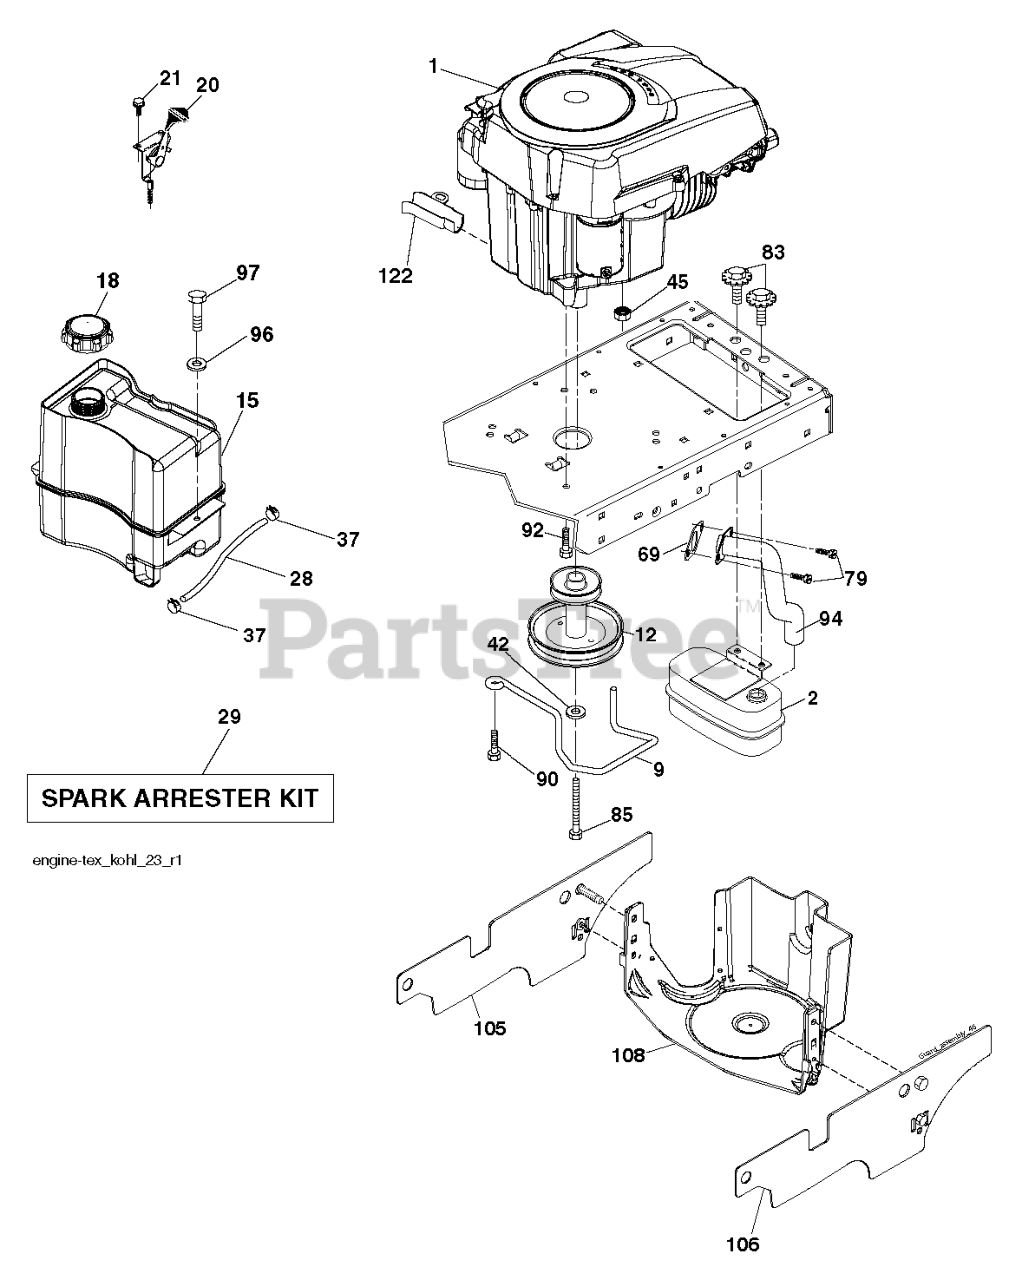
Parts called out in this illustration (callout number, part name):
2	MUFFLER.SINGLE.CYL.KOHL/B&S
9	KEEPER.BELT.ENGINE.3.25 (3 2)
12	PULLEY ENGINE
15	RP TANK FUEL FRT 1.5 GAL
18	CAP ASM.FUEL.2.25"FR.
20	CONTROL.TH/CK.C.
21	SCREW.#10 X 0.750.BOS
28	LINE.FUEL.20
29	KIT.SPARK ARRESTOR 794945 B&S
37	HOSE CLAMP
42	LOCKWASHER
45	NUT
69	GASKET.EXHAUST.KOHLER
79	SCREW.SOCKET HD.5/16-1
83	BOLT.5/16-18UNCX3/4 W/SEMS.BLK
85	BOLT HEX 7/16-20X4-1/4"
90	SCREW 3/8-16X1
92	SCREW 3/8-16X1
94	RP.TUBE.EXHAUST.KOHL.COURAGE
97	SCREW HEXWSHR 1/4-20X3/4
108	ENGINE COVER
122	EXTENSION DRAIN OIL
